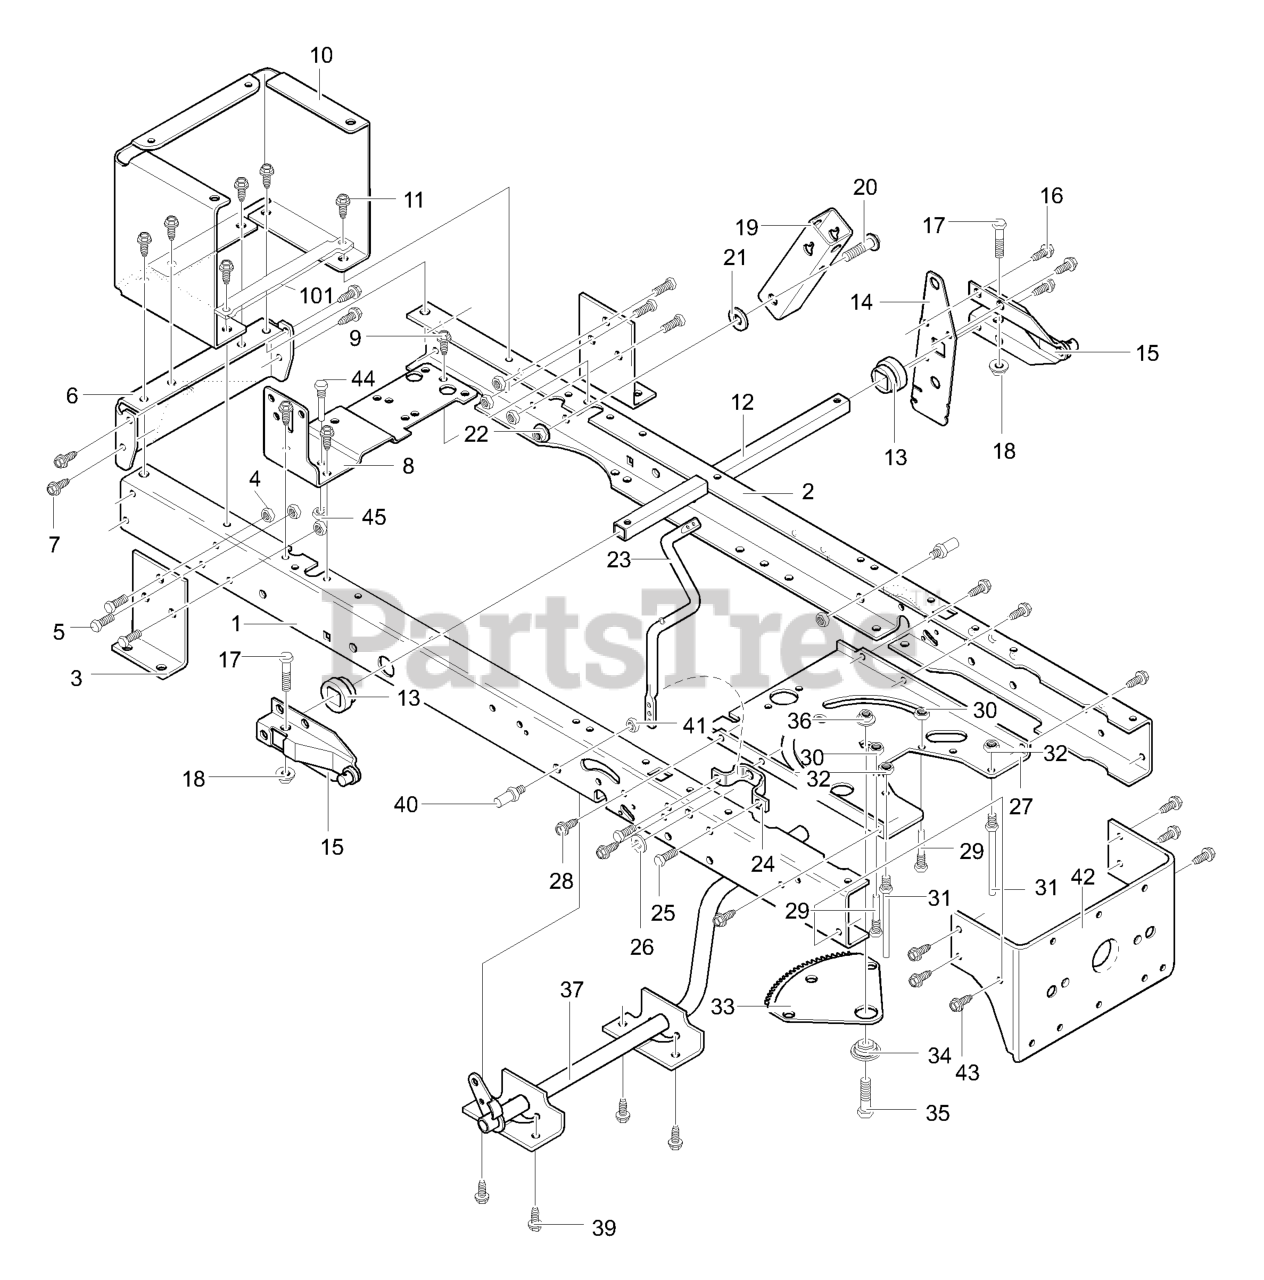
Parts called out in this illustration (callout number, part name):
1	Frame, Rail RH
2	Frame, Rail LH
3	Bracket, Transaxle
4	Nut, .32-18 Flange Ctrlk
5	Screw, .312-18x.75
6	Hitch Plate
7	Screw, .312-18x.75
8	Bracket, Shift RH
9	Screw, .312-18x.75
10	Rear Panel
11	Screw, .312-18x.75
12	Lifter Tube
13	Bushing, Lift Arm
14	Plate, Lift Arm
15	Lever, Lift Arm
16	Screw .31x.50
17	Screw, .5/16-21x1.25
18	Nut, .32-24 Flangelock
19	Pivot Bracket
20	Bolt, 3/8 HHSH
21	Flat washer
22	Nut, .38-16 Flange Ctrlk
23	PTO Crank
24	Bracket, Bell Crank
25	Screw, .312-18x.75
26	Flat washer
27	Steering Plate
28	Screw, .312-18x.75
29	Screw Guide 5/16-18
30	Nut, .32-18 Flangelock
31	Screw Guide
32	Nut, .32-18 Flangelock
33	Gear Sector
34	Bearing, Sector Gear
35	CAPSCREW, Hex Head, 5/16-18 x 1
36	Nut, 5/16 Hkeps
37	Asm. Brake Pedal
39	Screw, .312-18x.75
40	Pin, Threaded Shoulder
41	Nut, 3/8-16 Hwdfl Whiz
42	Bracket, Hanger Rear
43	Screw, .312-18x.75
44	Screw Guide 5/16-18
45	Nut, .32-18 Flangelock
93	Flat washer
101	Bracket, Battery Support
